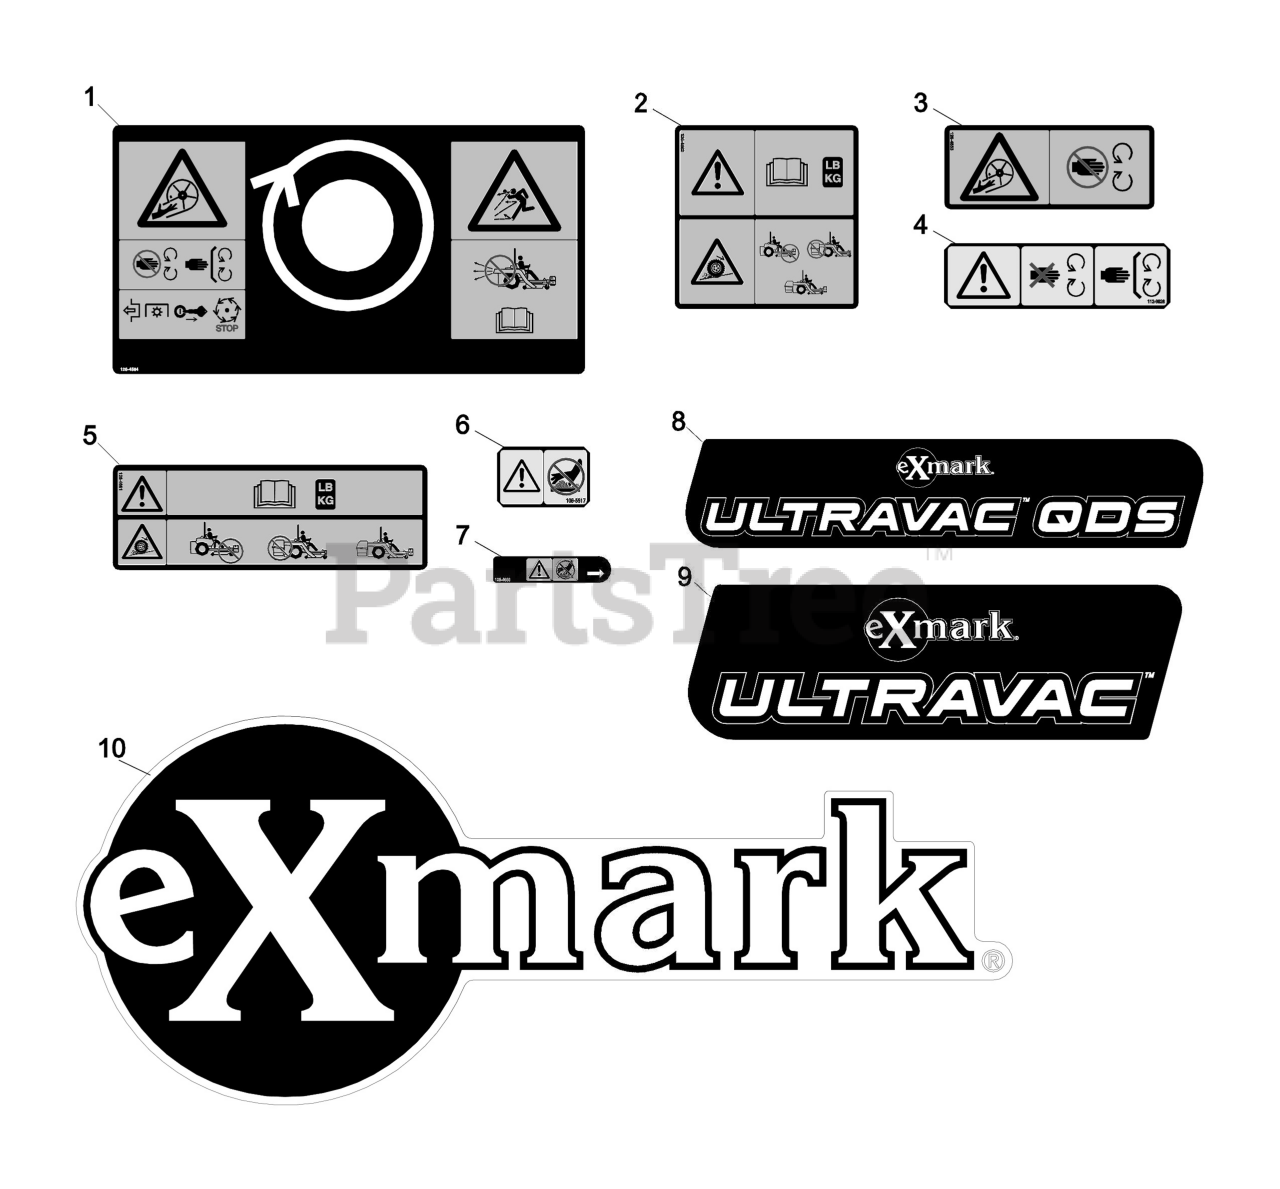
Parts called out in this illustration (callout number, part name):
1	Decal-Warning Blower
2	DECAL-WARNING, TRACTION
3	Decal-Blower-Impeller Hazard
4	DECAL-COVER, MISSING
5	DECAL-WARNING WEIGHT
6	DECAL-WARNING
7	DECAL-WARNING
8	Decal, UltraVac QDS
9	Decal, Ultra Vac
10	DECAL-EXMARK LOGO
